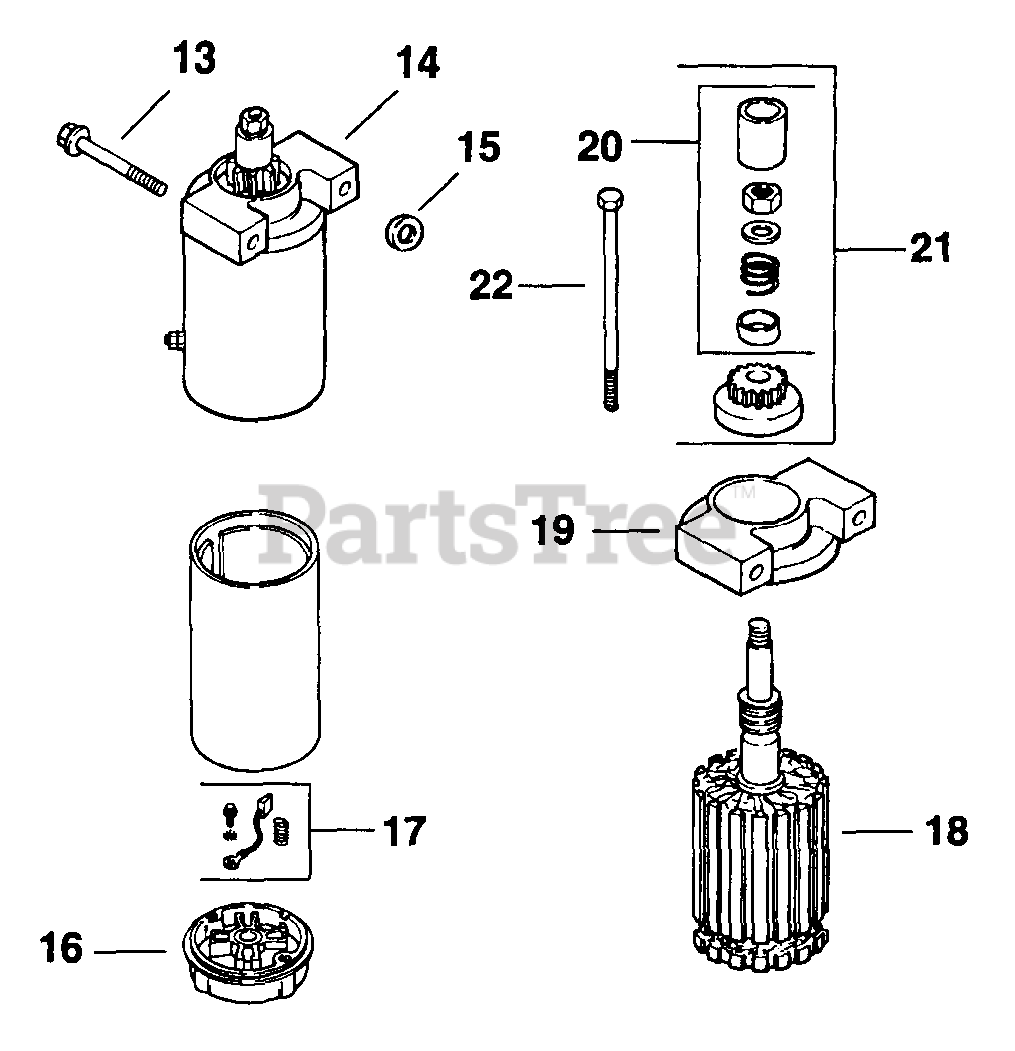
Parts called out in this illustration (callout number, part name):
16	Cap, Commutator End
17	Kit, Brush & Spring
18	Armature
19	Cap, Drive End
20	Kit, Drive Parts
21	Kit, Drive
22	Screw, Hex. Flange 1/4-20x4-1/4"
